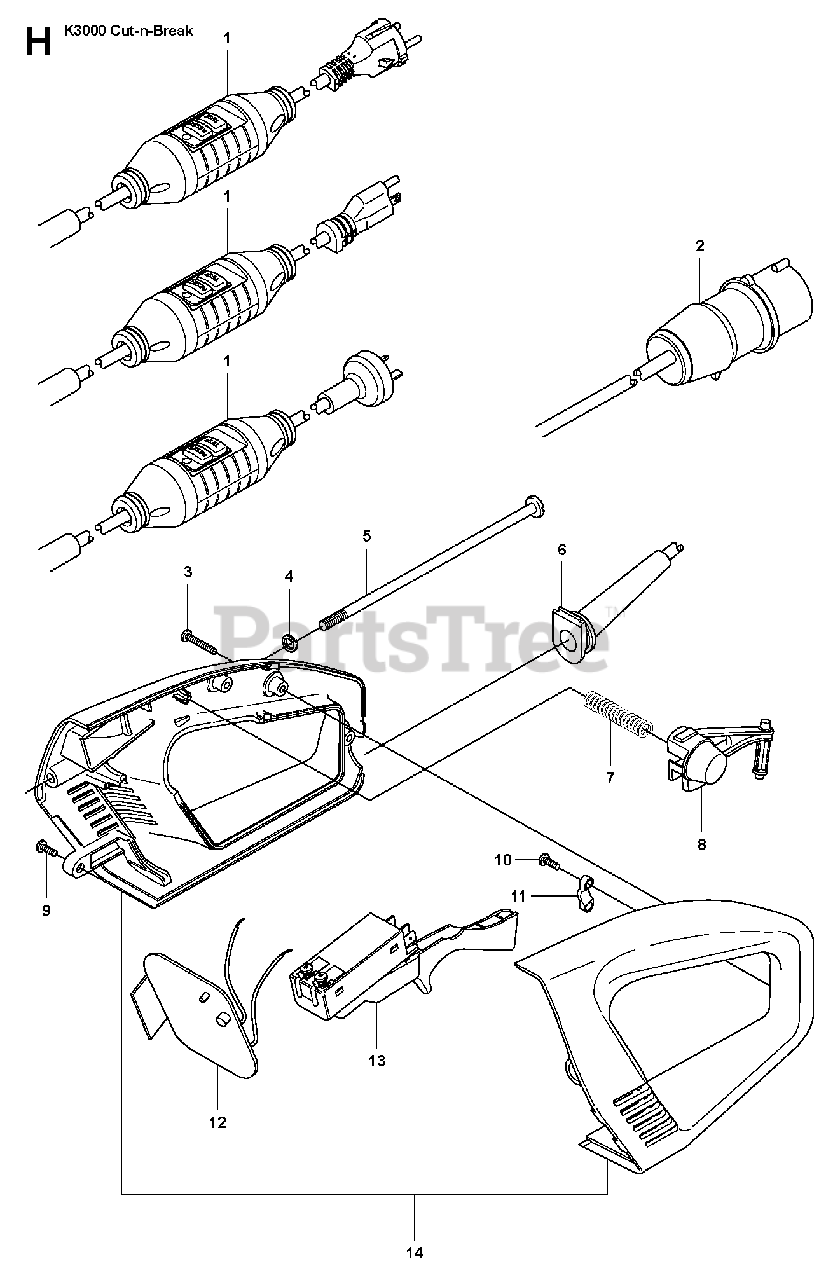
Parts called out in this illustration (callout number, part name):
1	CABLE110V JP, USA
4	SPRING WASHER
6	CABLE SLEEVE230V
7	SPRING
8	LOCKING BUTTON
9	SCREW CRPANM
12	PRINTED CIRCUIT ASSY110V
12	PRINTED CIRCUIT ASSY230V
14	HANDLE ASSY
